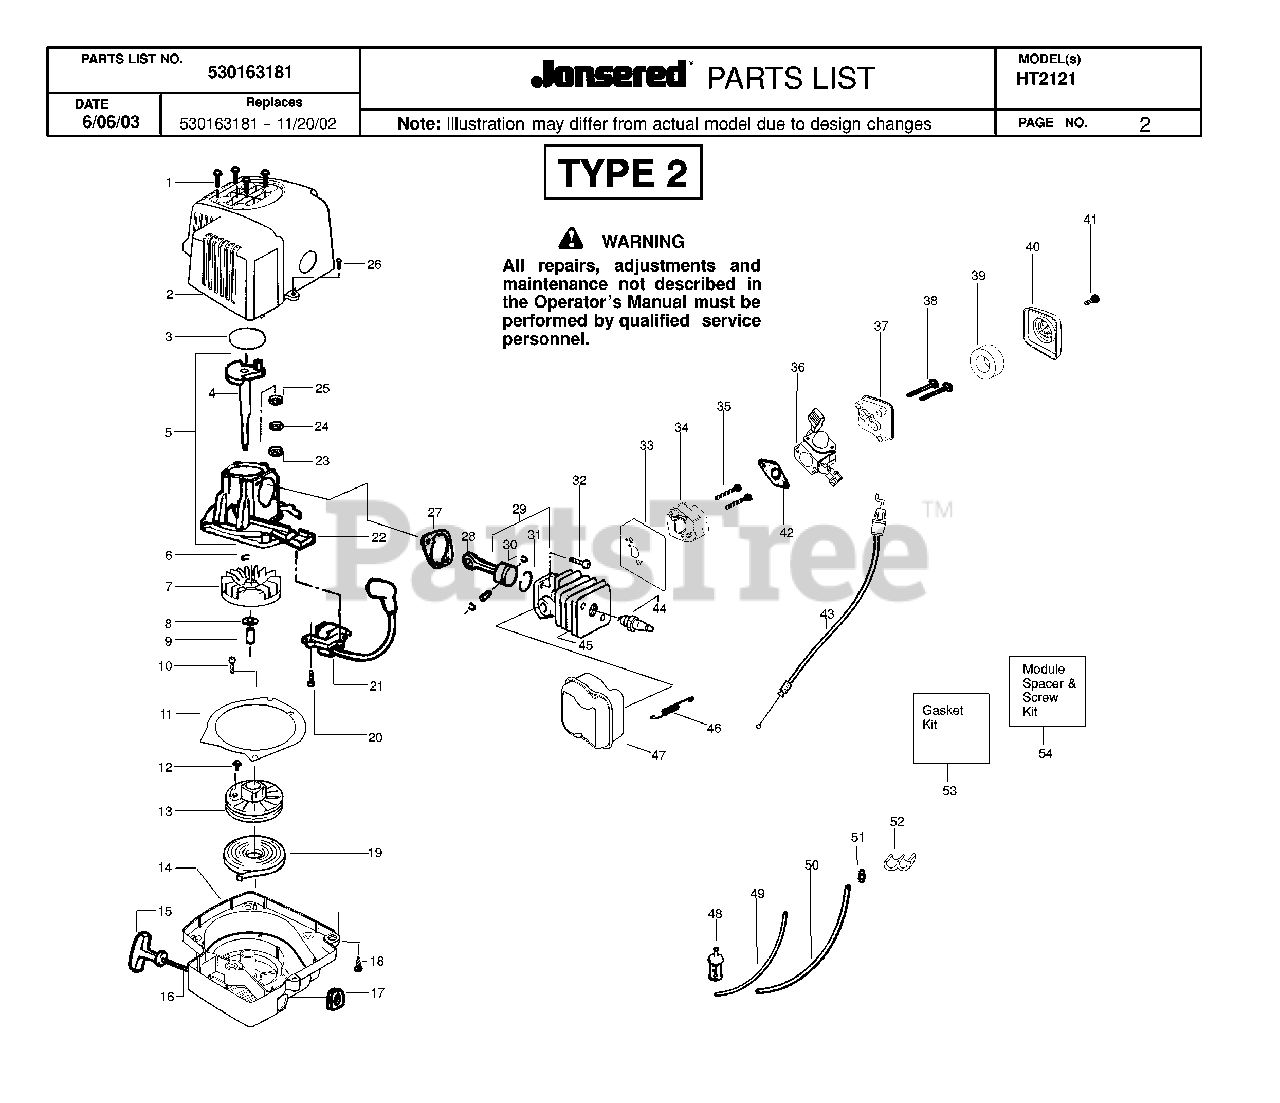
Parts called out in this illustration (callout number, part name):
2	ASSY-SHROUD
3	GASKET KIT
4	CRANKSHAFT
6	RETAINING RING
7	FLYWHEEL
8	WASHER FLAT
10	SCREW-10-16 X 1/2 HI-LO
11	PLATE-BAFFLE
13	STARTER PULLEY
14	FAN HOUSING
15	HANDLE-STARTER
19	STARTER SPRING
21	IGNITION MODULE
23	OUTER BEARING
24	KIT-CRANKCASE SEAL
25	BEARING
27	GASKET KIT
29	PISTON
30	WRIST PIN RET.
31	PISTON RING
33	GASKET KIT
34	ADAPTER-CARBURETOR
35	SCREW - CARB. ADAPTOR
36	CARBURETOR ASSY (C1U-W13A)
40	AIR FILTER COVER
42	GASKET KIT
43	ASSY-THROTTLE CABLE
44	PLUG-SPARK (RCJ-6Y)
45	KIT-CYLINDER
47	KIT-SPARK MUFFLER
48	ASSY-PICK-UP
51	FUEL LINE FITTING
53	GASKET KIT
